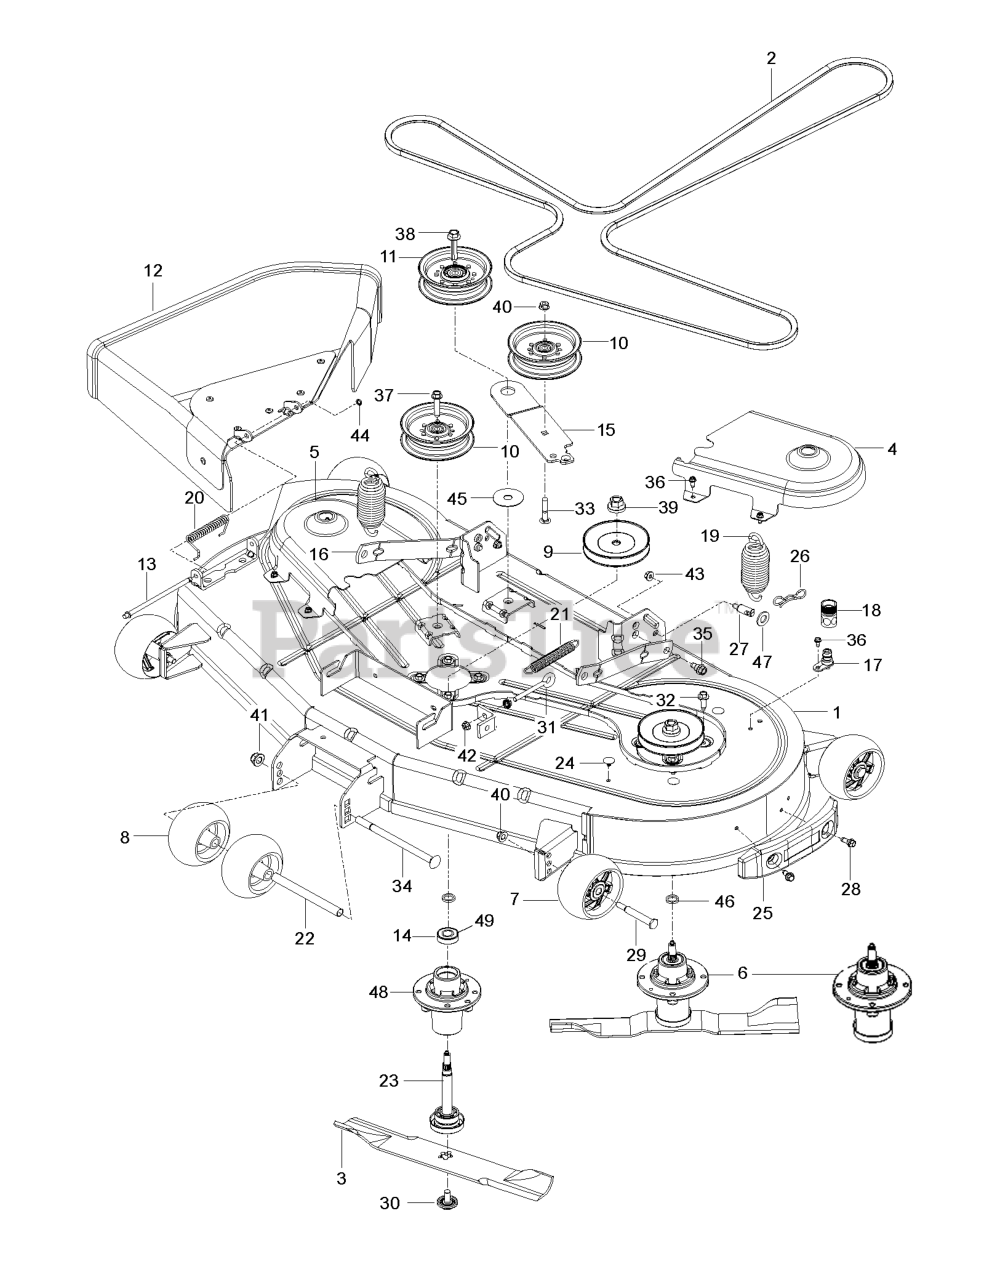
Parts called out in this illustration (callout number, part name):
1	DECK.SVC.54.CLRCT.RZ.MS668
1	DECK SVC.54.CLRCT.RZ.MS668
2	BELT.54CC.DRIVE.DECK.RZ.LONG
3	BLADE CC54 PZ STYLE HI LIFT BL
4	COVER.PNT.54CC.MNDRL.LH.ZTR.GY
5	COVER 54 CLEARCUT RH MANDREL G
6	MANDREL ASM, CAST IRON
7	WHEEL.GAUGE.RALLY
8	ROLLER, GAUGE .635 BORN
9	PULLEY.MANDREL.CRD 107CM.DOM.
10	PULLEY.IDLER.2006
11	RB PULLEY.IDLER.4.50/HUB SPEC
12	DEFLECTOR ASSY 54 CLEARCUT RES
13	ROD.HINGE
15	ARM IDLER ARM, CLEARCUT 54 BLA
16	ARM.RFIXED.MOWER.SUSPNSIONX431
17	PORT.WASHOUT
18	COUPLING.QUICK CONNECT
20	SPRING.42.FCS.DEFLECTOR
21	SPRING.EXTN.42.FCS.TR.DECK.DRV
22	TUBE, ROLLER AXLE LONG
23	SHAFT ASM MANDREL
24	PLUG CHRISTMAS TREE
25	BUMPER ASSY 54 CLEARCUT TRIM S
26	PIN.COTTER.7/16.BOW TI.
27	STUD.FASTNER.W/ANTI-ROTATE
28	SHOULDER BOLT 5/16-18TT
29	BOLT.SHOULDER.3/8-16X3-5/8.
30	BOLT.WASHER.ASM.7/16-2
31	EYE BOLT 5/16 X 3.50
32	BOLT.HEX.WASHR.HED.313-18X1.19
34	RHSNB 1/2-13 X 8 GR5 ZD
35	BOLT.SHOULDER
36	SCREW.1/4-20X5/8
37	SCREW LT
38	SCREW.7/16-14 X 2.125.WASHER
39	NUT.FLANGE.LOCK.TOP
40	NUT LOCK FLG 3/8-16 UNC
41	NUT, 1/2-13 HEX FLG NYLOC ZD
42	NUT 5/16C WHIZ
43	NUT LOCK HEX FLANGE 5/16-18
44	NUT PUSH M
46	WASHER.SPACER.MANDREL
47	WASHER.CLEAR.ZINC
48	MANDREL, HOUSING - CAST IRON
49	WASHER.SPACER.MANDREL
